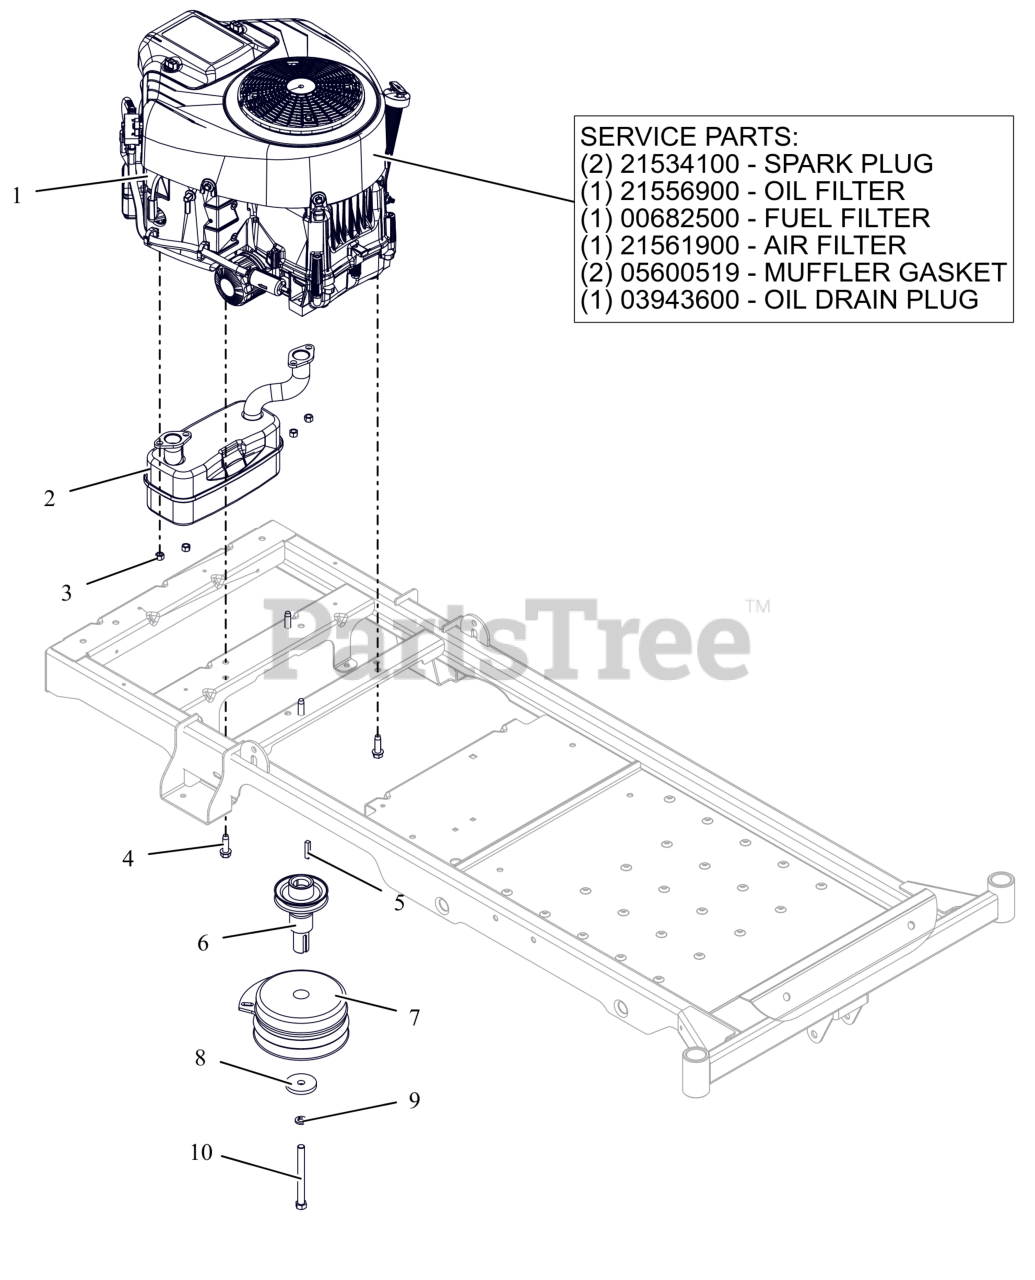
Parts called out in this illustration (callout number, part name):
1	ENGINE, BRIGGS 20 HP
1	PLUG, SPARK
1	OIL FILTER, BRIGGS
1	GASOLINE FILTER, BRIGGS
1	AIR FILTER, BRIGGS
1	GASKET, MUFFLER BRIGGS 690970
1	DRAIN, OIL
2	MUFFLER, TWIN BRIGGS
3	NUT-LK-TOP-FLG M8 ZCC
4	SCR,TAP .375-16X1.25HWH TR ZCC
5	KEY-SQ .25 X 1.25 X .25 SAE
6	WLDMT, CRANK SHAFT ADAPTER- BRIGGS
7	CLUTCH, 105 FT*LB MONO POLE
8	WSHR, FLT .469X2.00X.250 ZCC
9	WSHR, LK-REG .438X.109 ZCC
10	BLT, HEX .44-20X4.50 G8 ZCC NT
